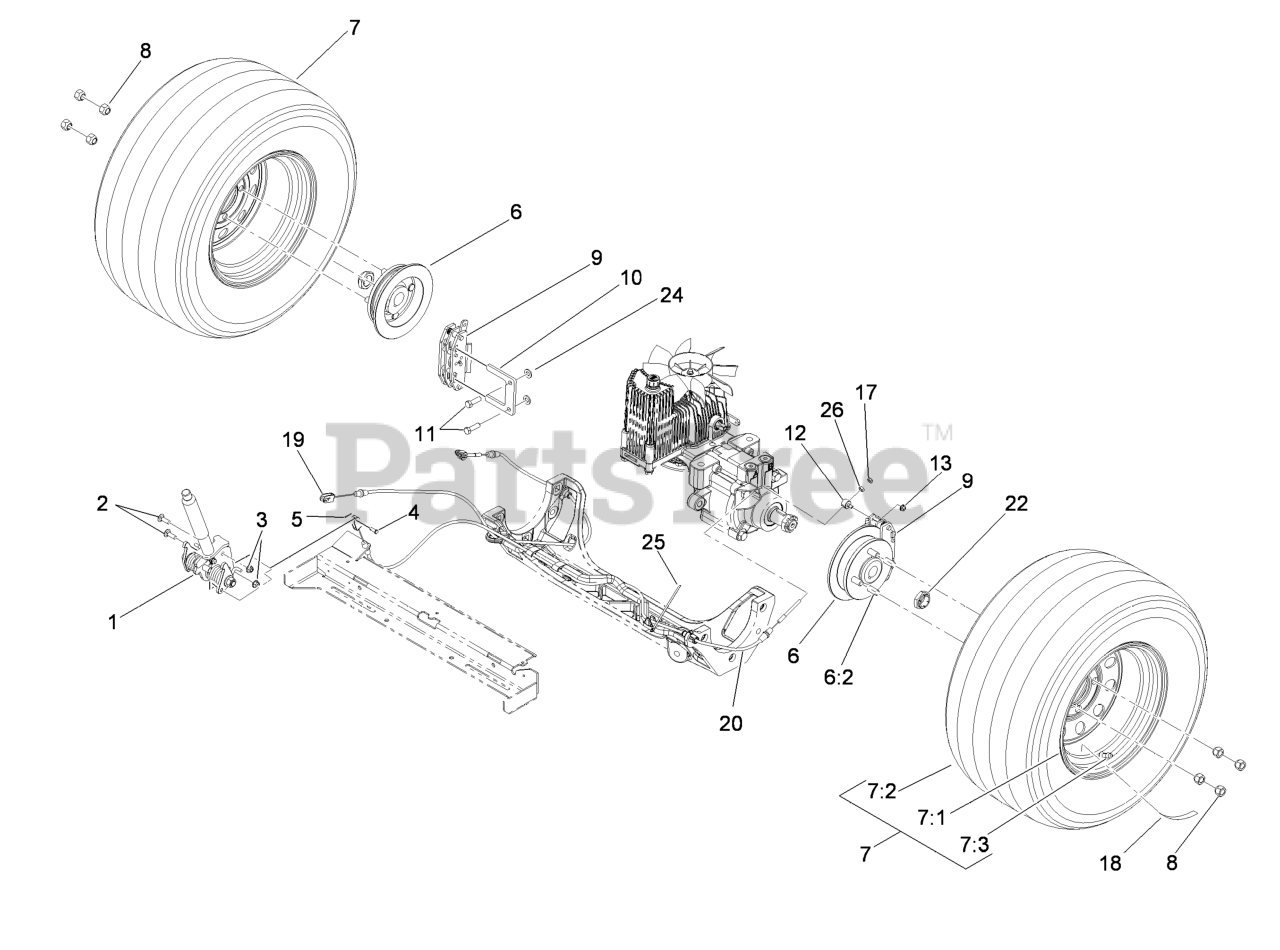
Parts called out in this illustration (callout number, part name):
1	BRAKE HANDLE ASM
2	BOLT-CARR
3	NUT-HF, NI
4	PIN-CLEVIS
5	PIN-COTTER
6	WHEEL HUB ASM
6:2	STUD-WHEEL
7	WHEEL AND TIRE ASM
7:1	RIM ASM
7:2	TIRE
7:3	Stem-Valve
8	NUT-LUG
9	CALIPER-BRAKE
10	PLATE-MOUNT, BRAKE
11	SCREW-LOCK, PATCH
17	NUT-LOCK, NI
22	LOCKNUT
24	WASHER-FLAT
25	TIE-CABLE
26	NUT-HEX
